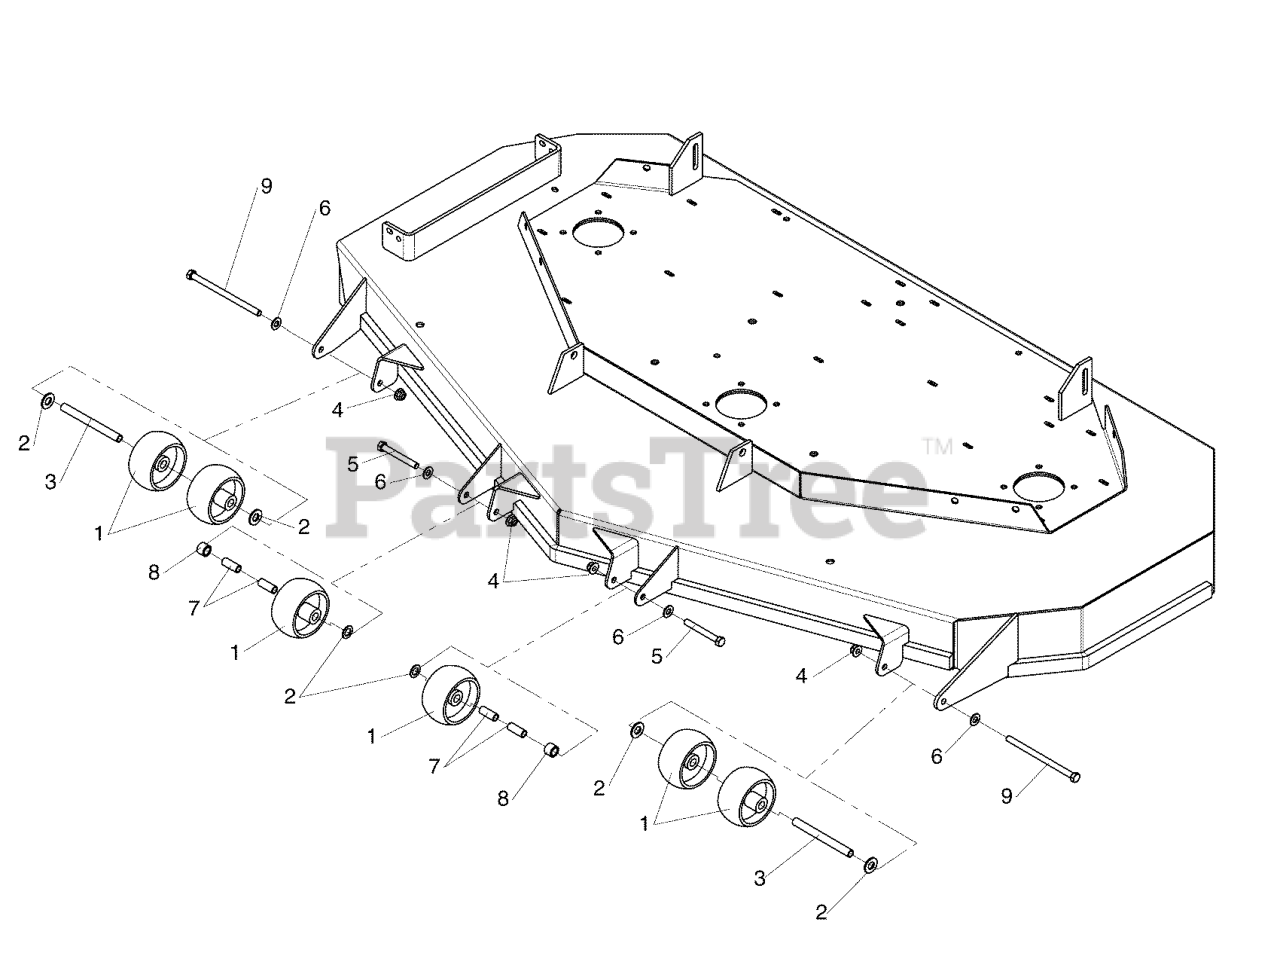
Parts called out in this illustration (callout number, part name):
1	WHEEL- 2.00 WIDE 3.88 DIA 0.531ID POLY
2	WASHER, 1/2" GD9 YZ
3	SPACER, .38 X .50 X 5.06
4	NUT, 3/8-16 HEX NYLOCK FLANGE
5	BOLT, 3/8-16 X 3" GD5 CZ
6	WASHER, 3/8 SAE
7	SPACER, .38 X .50 X 1.25, CZ
8	SPACER, .51 X .75 X .56
9	BOLT, 3/8-16 X 6" GD5 CZ
